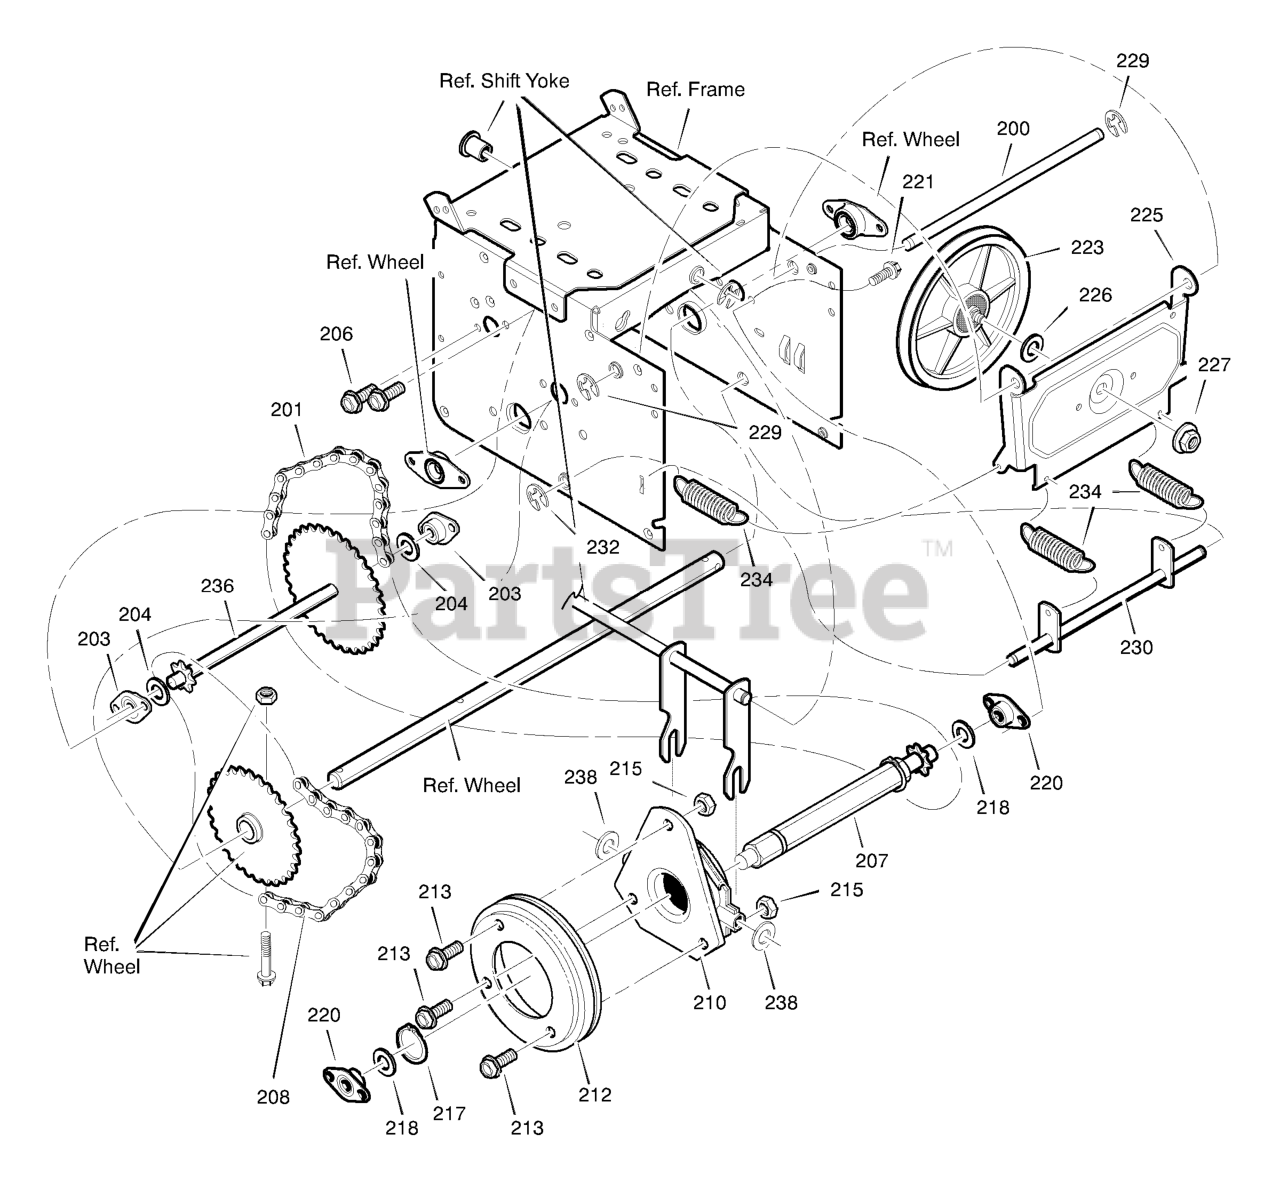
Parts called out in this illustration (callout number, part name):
200	LF AXLE, SWING PLATE YZ
201	CHAIN, ROLLER 19.00 LG
203	RETAINER, BEARING
206	SCREW, TAP 5/16-18 x 0.5
207	ASSY, HEX SHAFT
208	CHAIN, ROLLER 18.00 LG
210	BEARING, TRUNION CLUTCH R
212	WHEEL, FRICTION DISC
213	SCREW, 1/4-20 x 0.63
215	NUT, KEPS HEX 1/4-20
217	RING, RETEXT
220	RETAINER, BEARING
221	SCREW, TAP 5/16-18 X .50
223	ASSY, FRICTION PULLY
225	LF PLATE, SWINGING YZ
226	SPACER, FRICTION PULLEY
227	NUT, FLANGE LOCK 3/8-24
229	RETAINER, RING
230	LF ASSY, SPRING LINK YZ
232	RETAINER, RING
234	SPRING, EXTENSION
236	WLD, INTERMED SPROCKET 33T/7T
238	WASHER, FLAT
